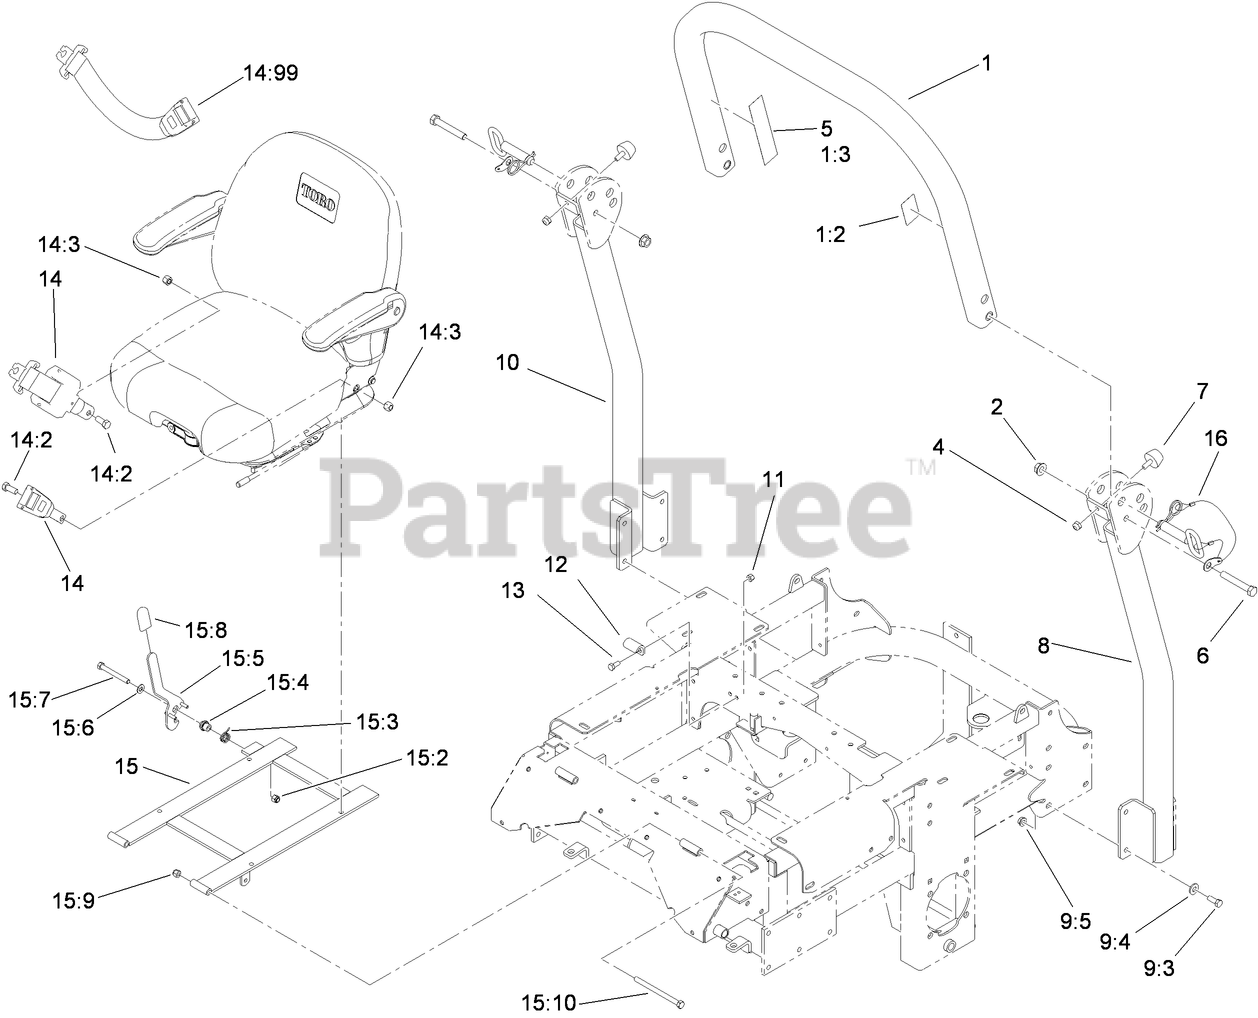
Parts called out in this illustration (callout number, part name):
1	Upper Tube ASM
1:2	DECAL-ROPS
1:3	DECAL-WARNING, FOLDING ROPS
2	NUT-HF
4	NUT-LOCK, NI
5	DECAL-WARNING
6	SCREW-HH
7	BUMPER-RUBBER
8	TUBE-SUPPORT, LH
9	BAG-BOLT, ROPS
9:3	SCREW-HH
9:4	WASHER-BELLEVILLE
9:5	NUT-HHF, WHIZ
10	TUBE-SUPPORT, RH
11	NUT-LOCK, NI
12	Catch-Latch, Seat
13	SCREW-HH
14	RETRACTABLE SEATBELT KIT
14:2	SCREW-HH
14:3	NUT-LOCK
14:99	SEAT BELT EXTENSION KIT
15	SEATFRAME ASM
15:2	NUT-LOCK, NI
15:3	SPRING-TORSION
15:4	BUSHING-LATCH, SEAT
15:5	LATCH ASM
15:6	WASHER-FLAT
15:7	SCREW-HH
15:8	GRIP-LEVER
15:9	NUT-LOCK, NI
15:10	SCREW-HH
16	PIN-FOLD, ROPS
